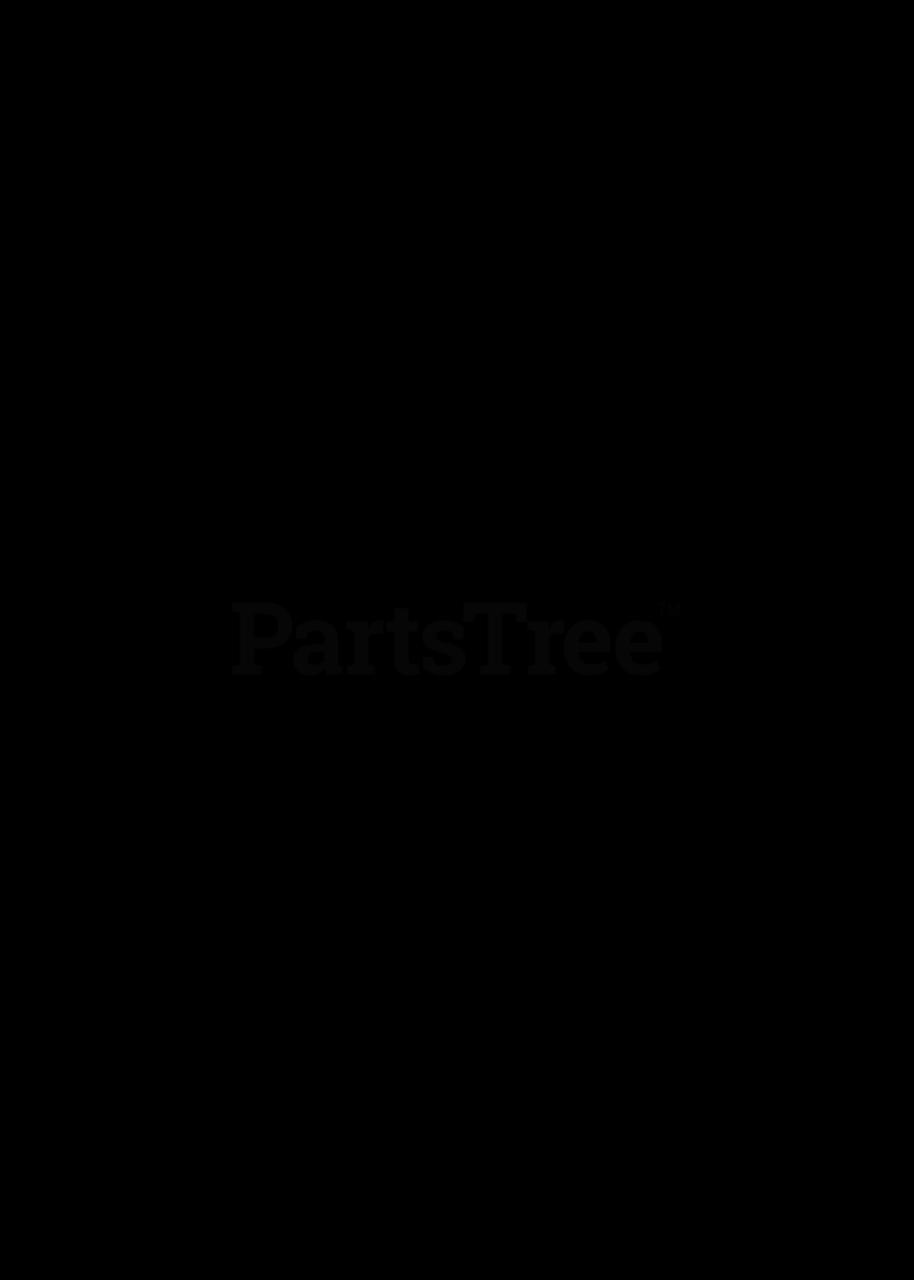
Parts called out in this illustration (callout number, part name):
3	WASHER BRB 8.4X17
5	LOCKNUT M8
11	CLAMP ASSY EXHAUST
12	HEAT SHIELD
14	SPRINGWASHER
17	VALUE.OIL.DRAIN
19	WASHER - 26X6.5X1.6
